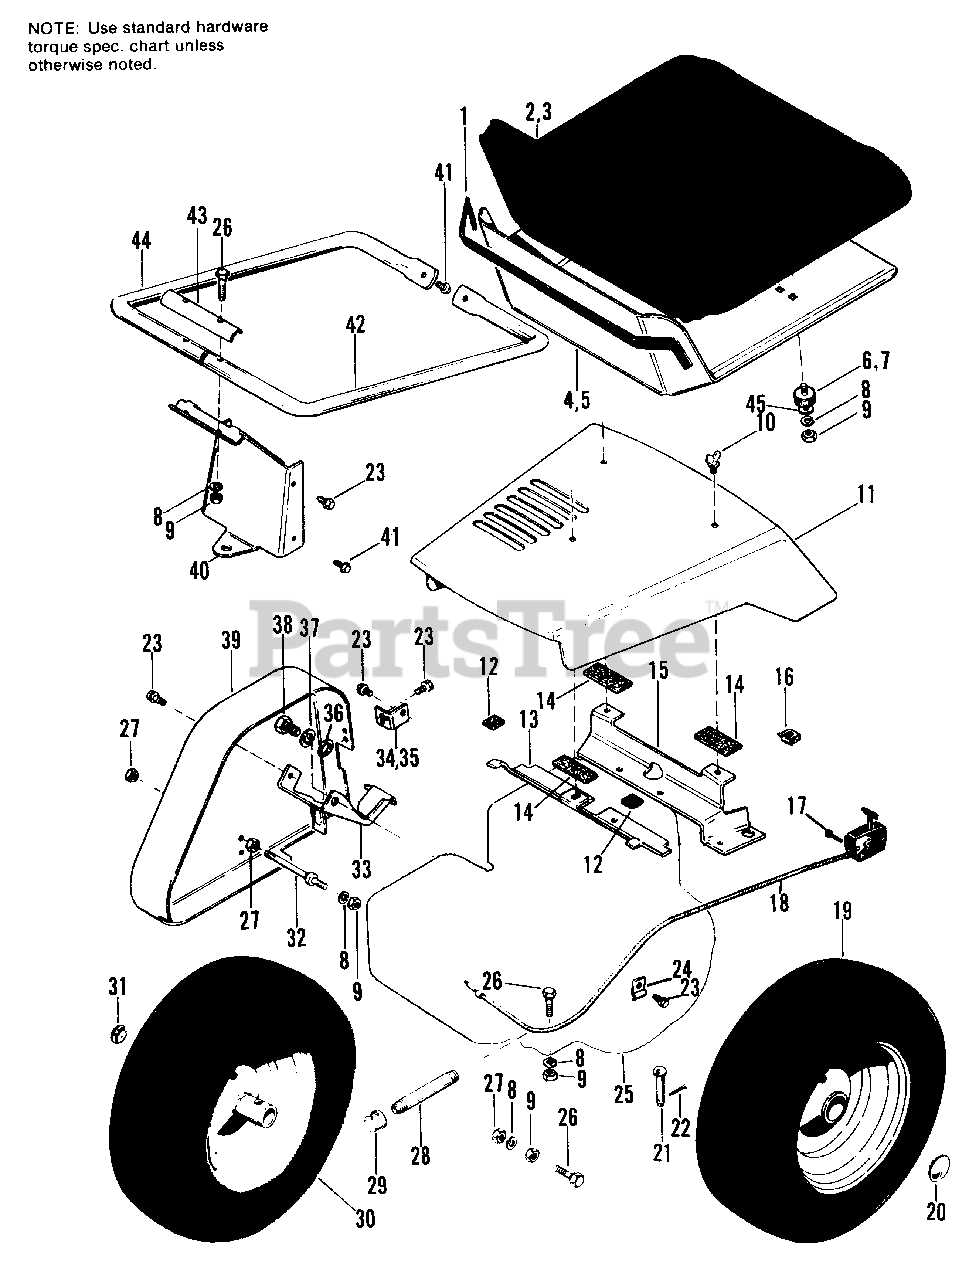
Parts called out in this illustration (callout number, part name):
1	TAPE, 2 ft.
2	PAD, Seat
3	PAD, Seat
4	PANEL, Seat
5	PANEL, Seat
6	CONNECTOR, Cushion
7	CONNECTOR, Cushion
8	LOCKWASHER, 5/16
9	NUT, Hex, Full, 5/16-18
10	SCREW, Thumb
11	HOOD ASSY.
12	BUTTON, Bumper
13	SUPPORT, Rear Hood
14	GASKET, Felt
15	SUPPORT, Front Hood
16	NUT, Tinnerman, 5/16-18
17	SCREW, Taptite, #10-24 x 1
18	THROTTLE & CHOKE ASSY.
19	WHEEL & TIRE ASSY., Rear, R.H.
20	BUTTON, Plug
21	PIN
22	PIN, Cotter, 1/8 x 3/4
23	SCREW, Taptite, 5/16-18 x 1/2
24	CLIP, Cable
26	CAPSCREW, Hex Hd., 5/16-18 x 1-1/2
27	LOCKNUT, Hex, 5/16-18
28	NIPPLE, Pipe
29	CAP, Pipe
30	WHEEL & WIRE ASSY., Rear, L.H.
31	BUTTON, Plug
33	STOP, Belt
34	BRACKET, Pulley Guard
35	BRACKET, Pulley Guard
36	WASHER, Plated, 1/2
37	LOCKWASHER, Int., 1/2
38	CAPSCREW, Hex Hd., 1/2-20 x 1
39	GUARD, Pulley
40	PLATE, Rear Hitch
41	SCREW, Taptite, 1/4-20 x 1/2
42	HANDLE, Rear, R.H.
43	BRACKET, Support, Handle
44	HANDLE, Rear, L.H.
45	WASHER, Plain, Plated, 5/16
